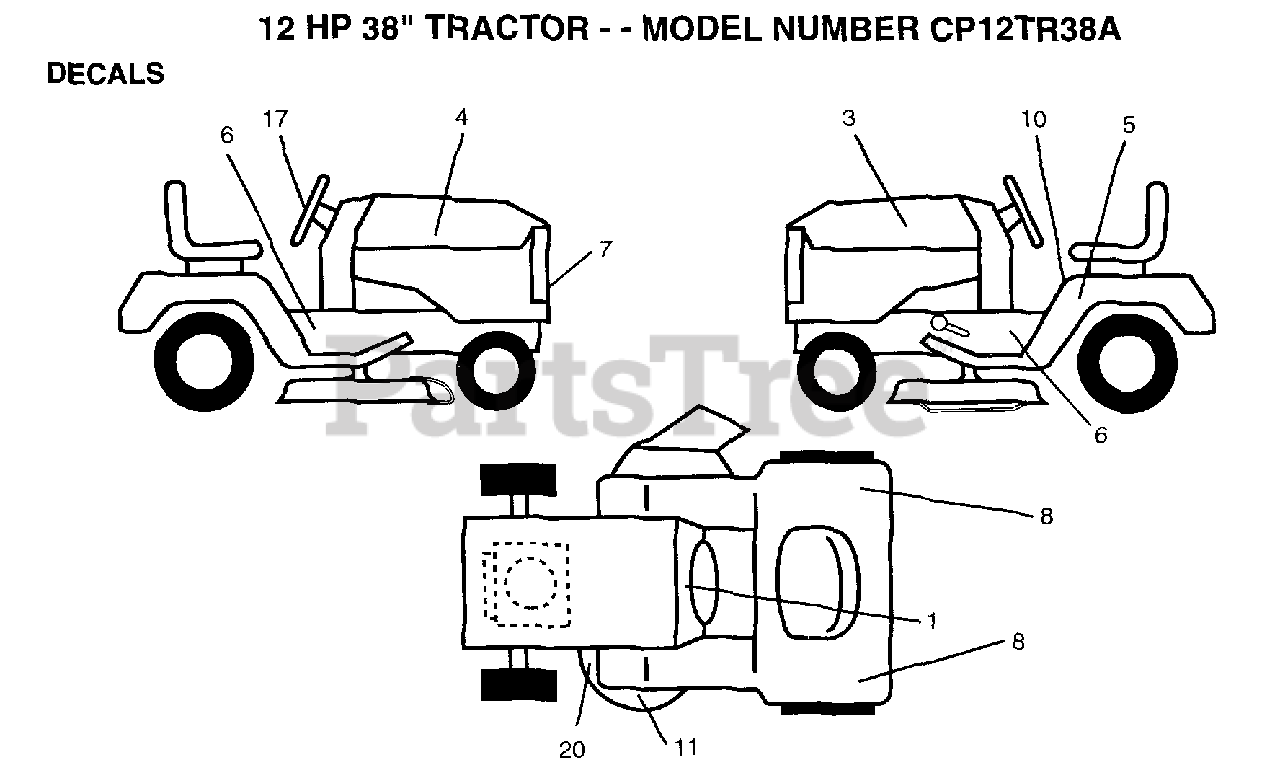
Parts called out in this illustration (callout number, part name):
1	DECAL.INST.OPER
3	DECAL.HOOD.LH
4	DECAL.HOOD.RH
5	IND HGT DECK DECA
6	"DECAL.CHASSIS.38"""
7	"DECAL,LIGHT BOX"
8	DECAL.FEND.QUICK.
10	DECAL
20	DECAL
